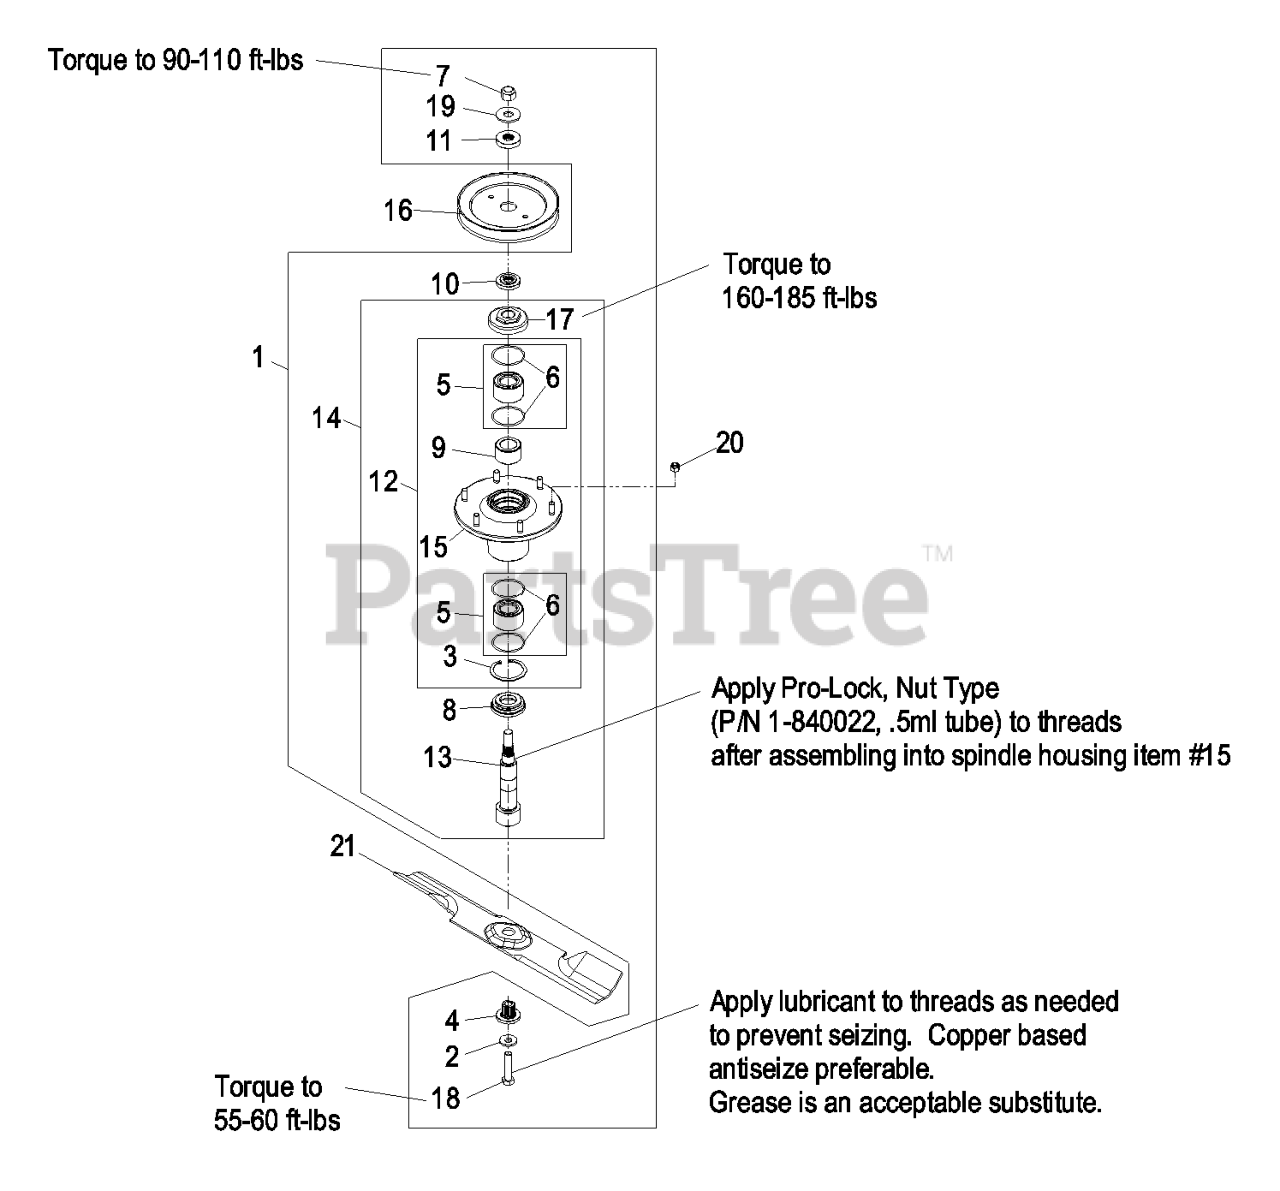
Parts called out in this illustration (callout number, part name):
1	ASM, CUTTER HSG W/MNT HRD
2	WASHER-SPRING
3	RING-RETAINING
4	BUSHING,SPLINED
5	ASM, BEARING W/ORINGS
7	NUT-LOCK NI
8	GUARD,BOTTOM
9	SPACER,BEARING
10	SPACER,SPLINED STEPPED
11	SPACER,SPLINED
12	ASM,CUTTER HOUSING
15	ASM,HOUSING W/STUDS
16	SHEAVE,BLADE DRIVE 6.75
18	SCREW-HH
19	WASHER-FLAT
20	NUT-LOCK, NI
